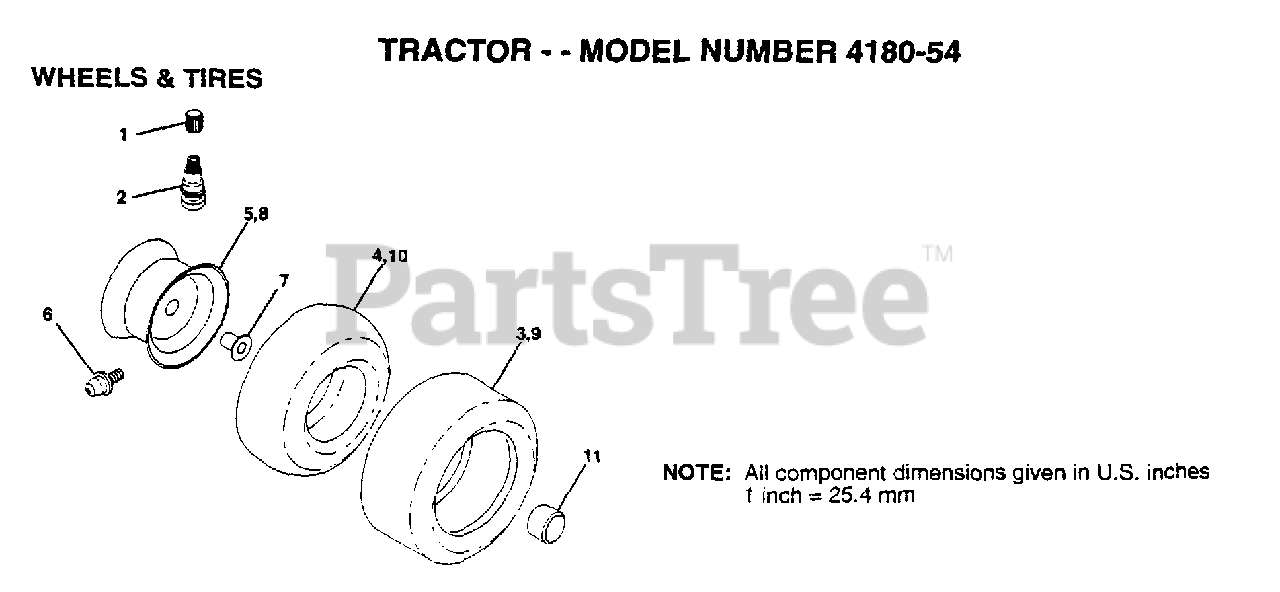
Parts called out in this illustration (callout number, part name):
1	VALVE CAP
2	VALVE STEM LT
4	TUBE.5.3/4.5/6
5	RIM.FRONT.
6	FITTING LT
7	"FLANGE, BEARING"
8	RIM.REAR.417
10	TUBE.23X8/10-12
11	HUB CAP
